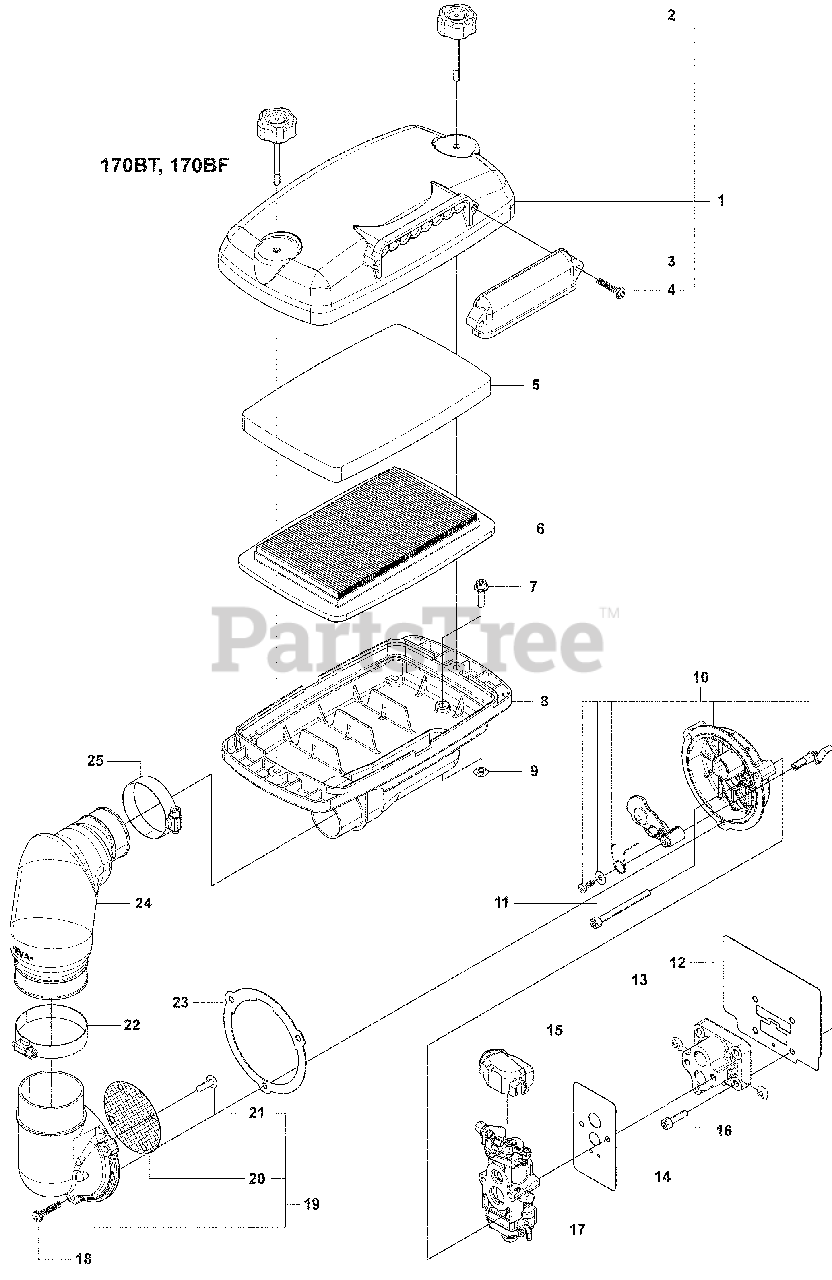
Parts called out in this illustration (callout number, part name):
1	Cover
4	Screw
5	Air Filter Element
6	Air Filter Element
7	Bolt
10	Cup Assembly
11	Bolt
12	Gasket
13	Insulator
14	Gasket
15	Cover
16	Bolt
17	Carburetor
18	Screw
19	Cup Cover Assembly
21	Screw
22	Clamp, F64
23	Gasket
24	HOSE
25	CLAMP(F51)
